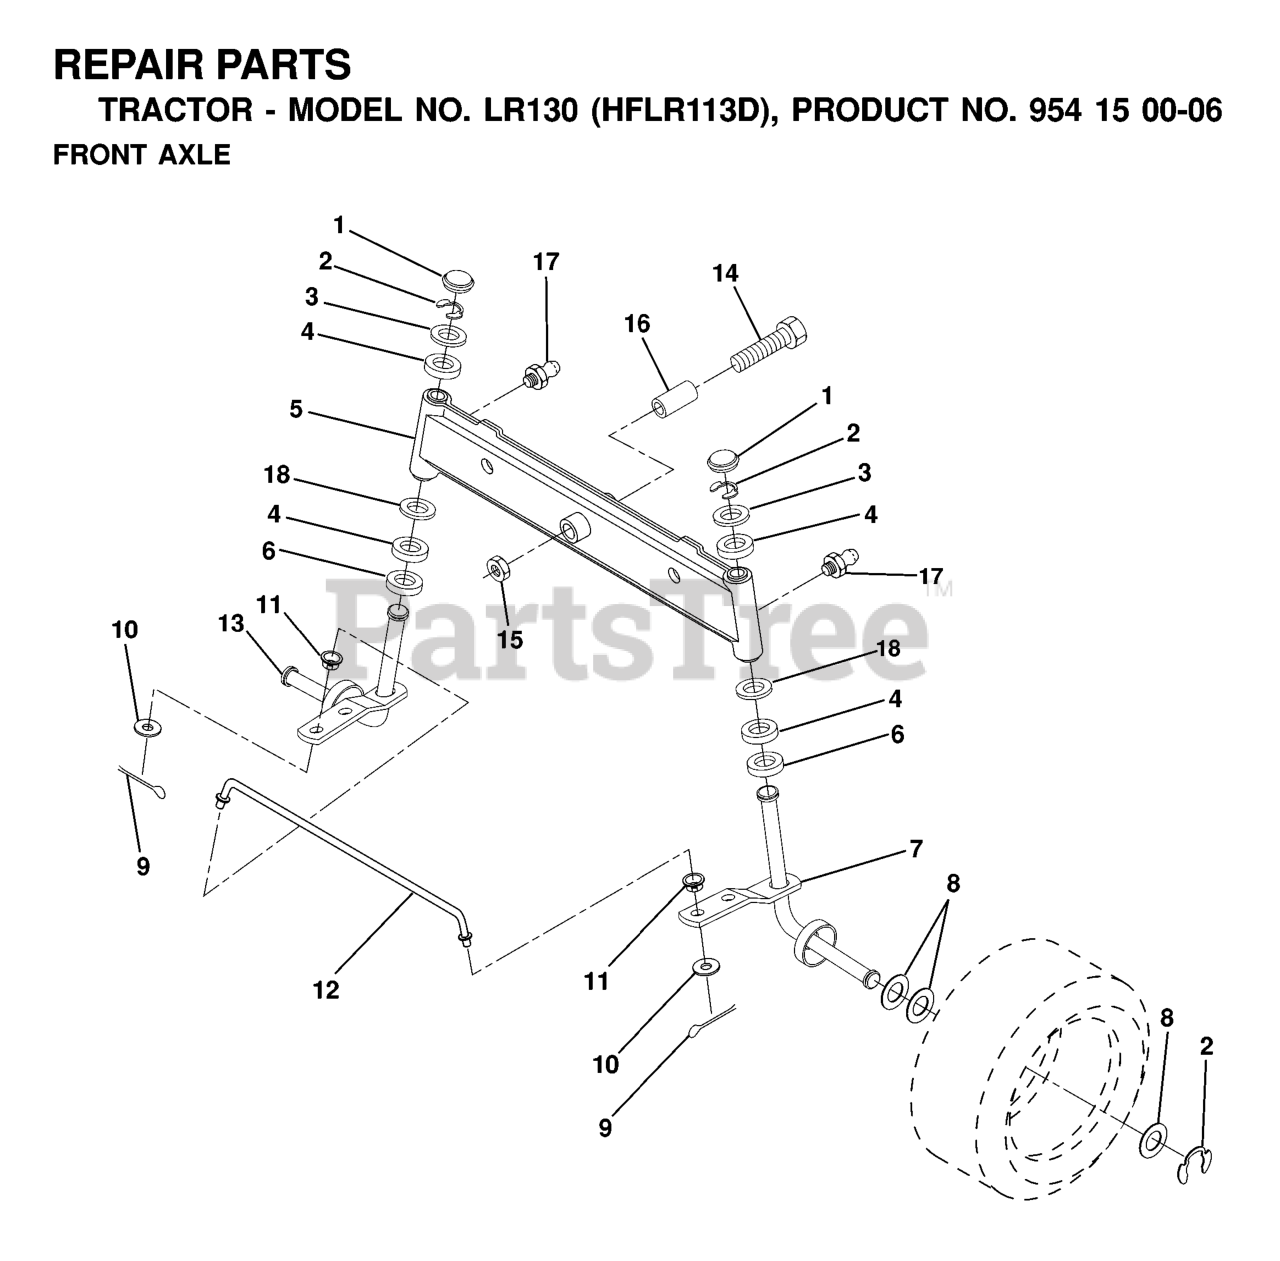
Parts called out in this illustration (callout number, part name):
1	CAP.SPINDLE.BLACK
4	BRNG T
6	THRUST WASHER
8	WASHER
9	COTTER PIN
10	WASHER
11	BUSHING.DRAGLINK (2 2)
12	TIE ROD
13	SPINDLE.ASSEM.LH
14	Bolt, Hex Head 5/8-11 x 3-1/2
15	NUT-LOC,FLANGE LT
16	BEARING
17	ZERK M
